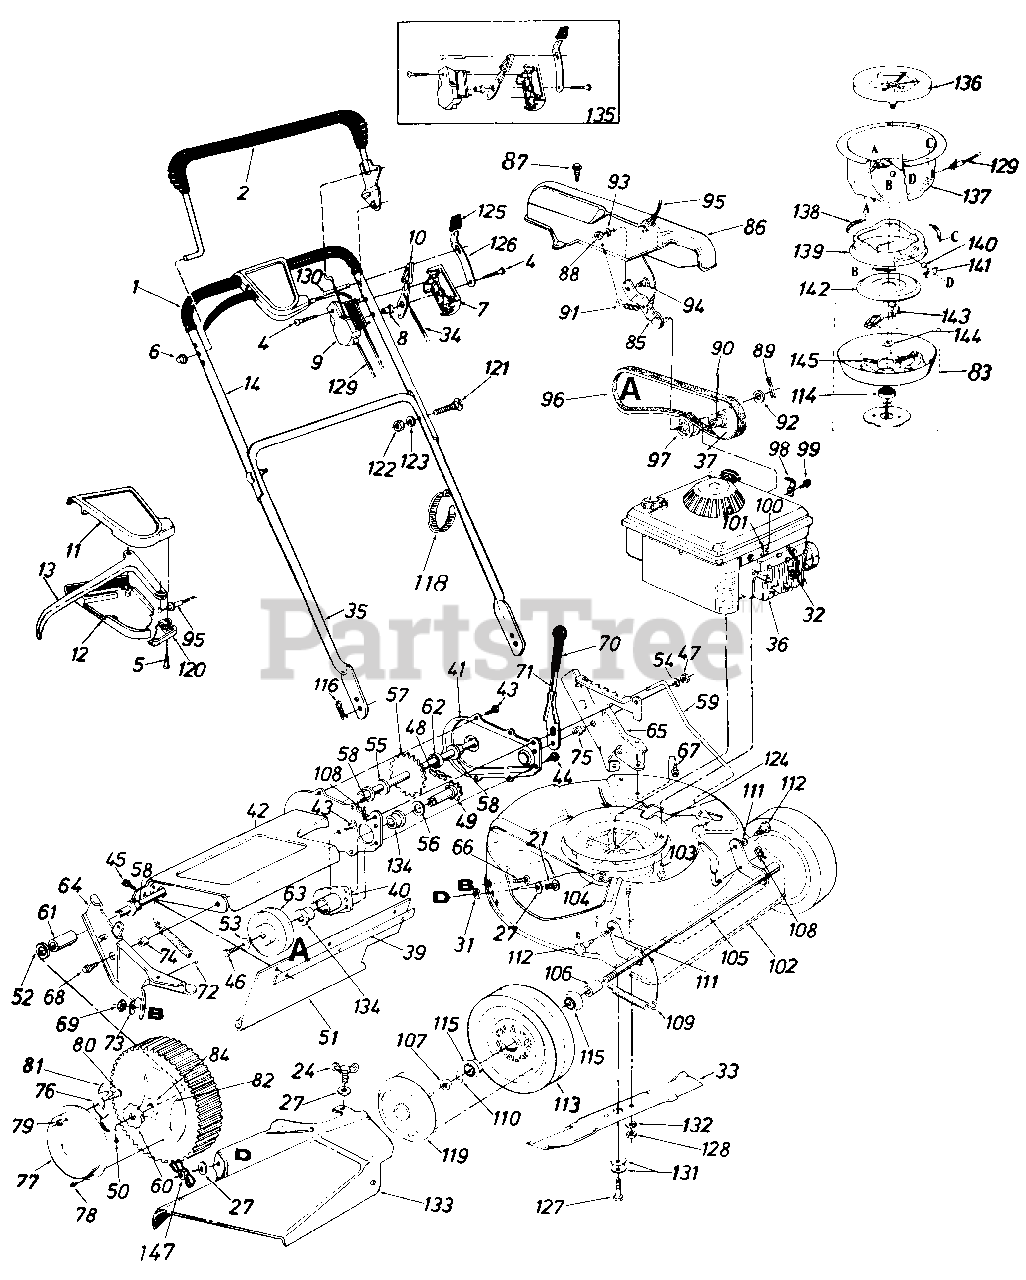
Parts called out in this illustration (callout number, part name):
1	Grip
2	Control Handle Ass'y. L.H.
4	Truss Mach. Scr. #12 x 1.50" Lg.
5	Fl-"C"-Sunk Hd. Tap Scr. #10 x .75" Lg.
6	Cap Speed Nut .31 Dia.
7	Control Panel Half
8	Control Disc Pin
9	Clutch Panel Half
10	Throttle Control Lever
11	Self-Propelled Control Cover
12	Self-Propelled Control Cover
13	Control Lever
14	Upper Handle Chrome
21	Carriage Bolt 1/4-20 x .62" Lg.*
24	Wing Bolt 1/4-20 x .62" Lg.
27	Fl-Wash. .280" I.D. x .620" O.D.
31	Bolt Retainer 1/4 x .50" O.D.
32	Spark Plug Insulator
34	Throttle Control Wire 58.0" Lg.
35	Lower Handle Chrome
36	Engine
37	Erigine Pulley 1/2"
39	Retaining Strip
40	Bearing Hub Flange Ass'y.
41	Chain Cover
42	Chain Axle Ass'y.
43	Hex B-Tap Scr. 1/4" x .38" Lg.
44	Hex Wash. S-Tap Scr. 1/4-20 x .50" Lg.
45	Hex AB-Tap Scr. 1/4 x .62" Lg.
46	Hex Wash. TT-Tap Scr. 1/4-20
47	Hex Patch L-Nut 3/8-24 Thd.
48	#48 Chain .500" Pitch x .30 Links
49	Sprocket Shaft Ass'y.
50	Cotter Pin 1/8" Dia. x 1.00" Lg.*
51	Rear Flap 3.75" x 17.30" Lg.
52	Fl-Wash. .531" I.D. x .930" O.D.
53	Bell-Wash. .265" I.D. x .75" O.D.
54	Fl-Wash. .385" I.D. x .87" O.D.
55	Fl-Wash. .510" I.D. x 1.0" O.D.
56	Fl-Wash. .62" I.D. x 1.12" O.D.
57	Rear Shaft Ass'y. 22.05" Lg.
58	Hex Flange Bearing .506" I.D. Plastic
59	Height Adj. Rod 1.50" x 19.42" Lg.
60	Ratchet Wheel 1.62" O.D.
61	Spacer.51" I.D. x .69" O.D. x .690" Lg.
62	Spacer.510" I.D. x 1.00" O.D. x .210" Lg.
63	1/2" "V"-Pulley
64	R.H. Handle Wheel Brkt. Ass'y.
65	L.H. Handle Wheel Brkt. Ass'y.
66	Carriage Bolt 5/16-18 x .62" Lg.
67	Hex Wash. Hd. B-Tap Scr. 5/16-1 8
68	Hex Wash. Hd. TT-Tap Scr. 3/8-1 6
69	Hex Nut 5/16-18 Thd.*
71	Height Adj. Lever 1.25 x 8.5" Lg.
72	Extension Spring .50" O.D. x 3.80" Lg.
73	Bell-Wash. .345" I.D. x .88" O.D.
74	Spacer.385" I.D. x .502" O.D. x .270" Lg.
75	Shld. Spacer.500" Dia. x .100
76	Spring Nylon
78	Pan Hd. Tap Scr. #12 x .50" Lg.
79	Hex ins. L-Nut 1/4-20 Thd.
80	Shld. Scr. .342" Dia. x .268
81	Pawl
82	Wheel Ass'y. Comp. Rear 8 x 1.75
83	Clutch Blade Housing Ass'y.
84	Flange Ball Bearing 1/2" I.D.
85	Belt Idler Bracket Ass'y.
86	Belt Cover
87	Hex Wash. S-Tap Scr. 1/4-20 x .50" Lg.
88	Hex Nut 1/4-20 Thd.*
89	Cotter Pin 1/8" Dia. x 1.00" Lg.*
90	Spring Pin Spir. 3/16" Dia. x 1.00" Lg.
91	Extension Spring .33" O.D. x 1.12" Lg.
92	Fl-Wash. .531" I.D. x .930" O.D. x .050
93	L-Wash. 1/4" I.D.*
94	Shld. Bolt .375" Dia. x .181
95	S.P. Cable x 53.0" Lg.
96	"V"-Belt 1/2" x 32.0" Lg.
97	Fl-ldler Plastic 1.62" Dia.
98	Throttle Control Cable Clip
99	Hex B-Tap Scr. #10 x .38" Lg.
100	Hex Sems Bolt #10-32 x .62" Lg.
101	Casing Clamp
104	Speed Nut 1/4-20 U-Type
105	Front Axle Ass'y
106	Sleeve 526" I.D. x .690" O.D. x .880" Lg.
107	Hex L-Nut 1/2-20 Thd.
108	Intern. Cotter Pin 5/16" Dia.
109	Extension Spring .50" O.D. x 3.20" Lg.
110	Fl-Wash. .531 " I.D. x .930" O.D.
111	Intern. L-Wash. 3/8 x .56" O.D.
112	Shld. Bolt .623" Dia. x .425
113	Front-Wheel Ass'y. Comp 7 x 1.75
114	Ball Brg. .669" I.D. x 1.574"
115	Flange Ball Bearing 1/2" I.D.
116	Intern. Cotter Pin 5/16" Dia.
119	Hub Cap Plastic
120	S.P. Control Cover
121	Curved Carr. Bolt 5/16-18 x 1.38" Lg.
122	Hex Nut 5/16-18 Thd.*
123	L-Wash. 5/16" I.D.*
124	Blade Brake Clutch Comp.
125	Spring Lever Knob
126	Lockout Spring
127	Hex Cent. L-Bolt 3/8-24 x 2.00" (Grade 8)
128	Hex Nut 3/8-24 Thd. (Grade 8)
129	BBC Clutch Cable x 46.0" Lg.
130	Lock Pin .314" Dia. x 1.75" Lg.
131	Bell-Wash. .400" I.D. x .88" O.D.
132	L-Wash. 3/8" I.D.
133	Side Chute Deflector
134	Flange Bushing
135	Kit Control Housing Comp.
137	Clutch Housing
138	Extension Spring .35 O.D. x 1.75" Lg.
139	Brake Cup Cone
140	Steel Ball .500" Dia.
142	Clutching Cone
143	Hex Tap L-Scr. 1/4-20 x .75" Lg.
144	Fl-Wash. .690" I.D. x 1.060" O.D.
145	Compression Spring .35" O.D. x 2.00" Lg.
8204-190-4	Hardware Pack
